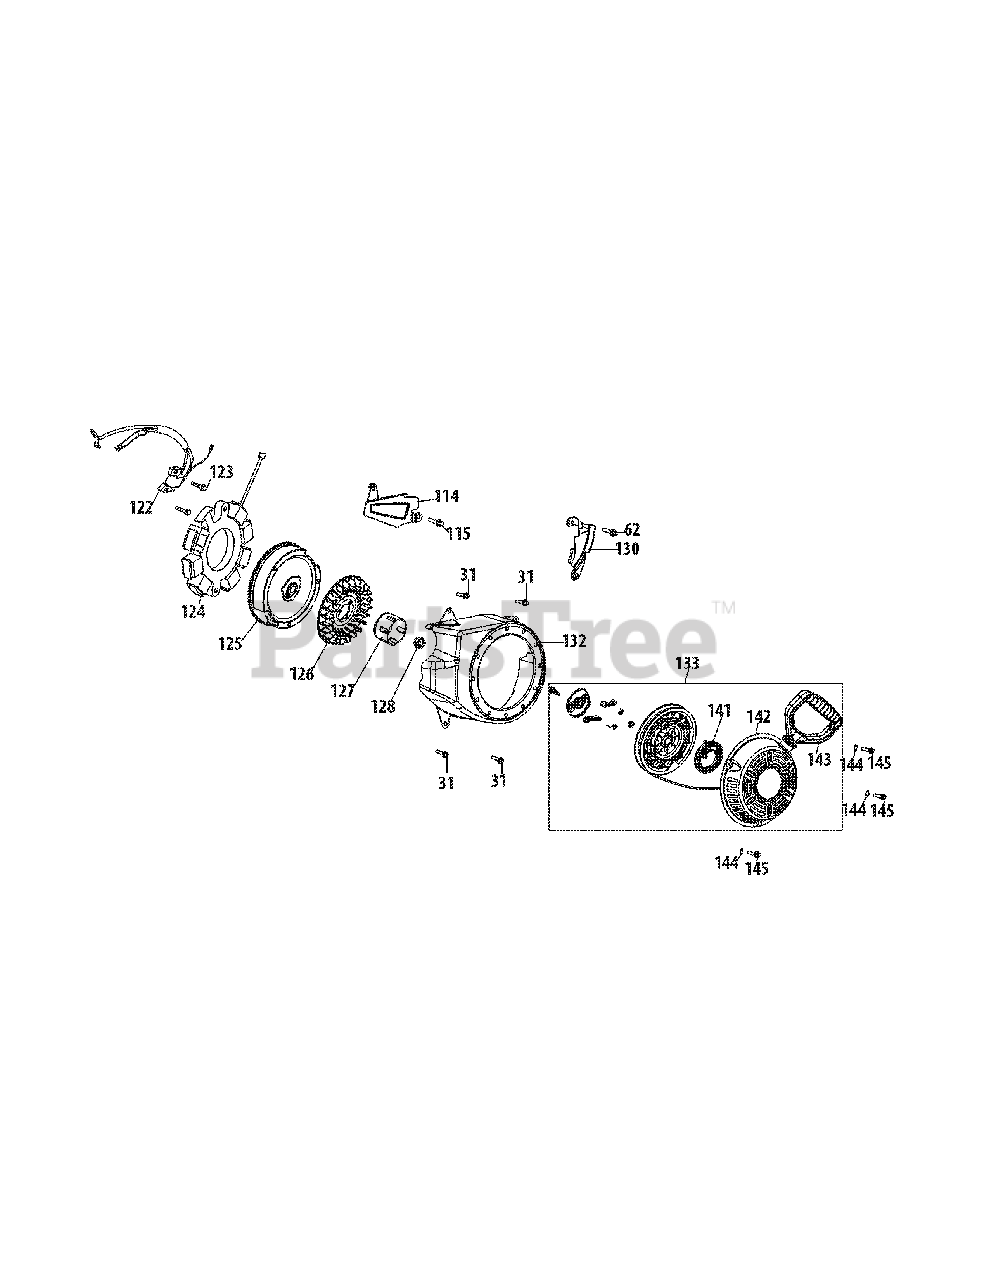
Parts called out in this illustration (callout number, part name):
31	Bolt, M6×12
62	Bolt, M6×12
114	Choke Plate
115	Bolt, M6×10
122	Ignition Module
123	Bolt, M6×25
124	Charging Coil
125	Flywheel
126	Cooling Fan
127	Starter Cup
128	Nut, M14×1.5
130	Lower Shield
132	Blower Housing
133	Recoil Starter
141	Recoil Spring
142	Starter Cover
143	Starter Handle
144	Washer, 6
145	Bolt M6×10
